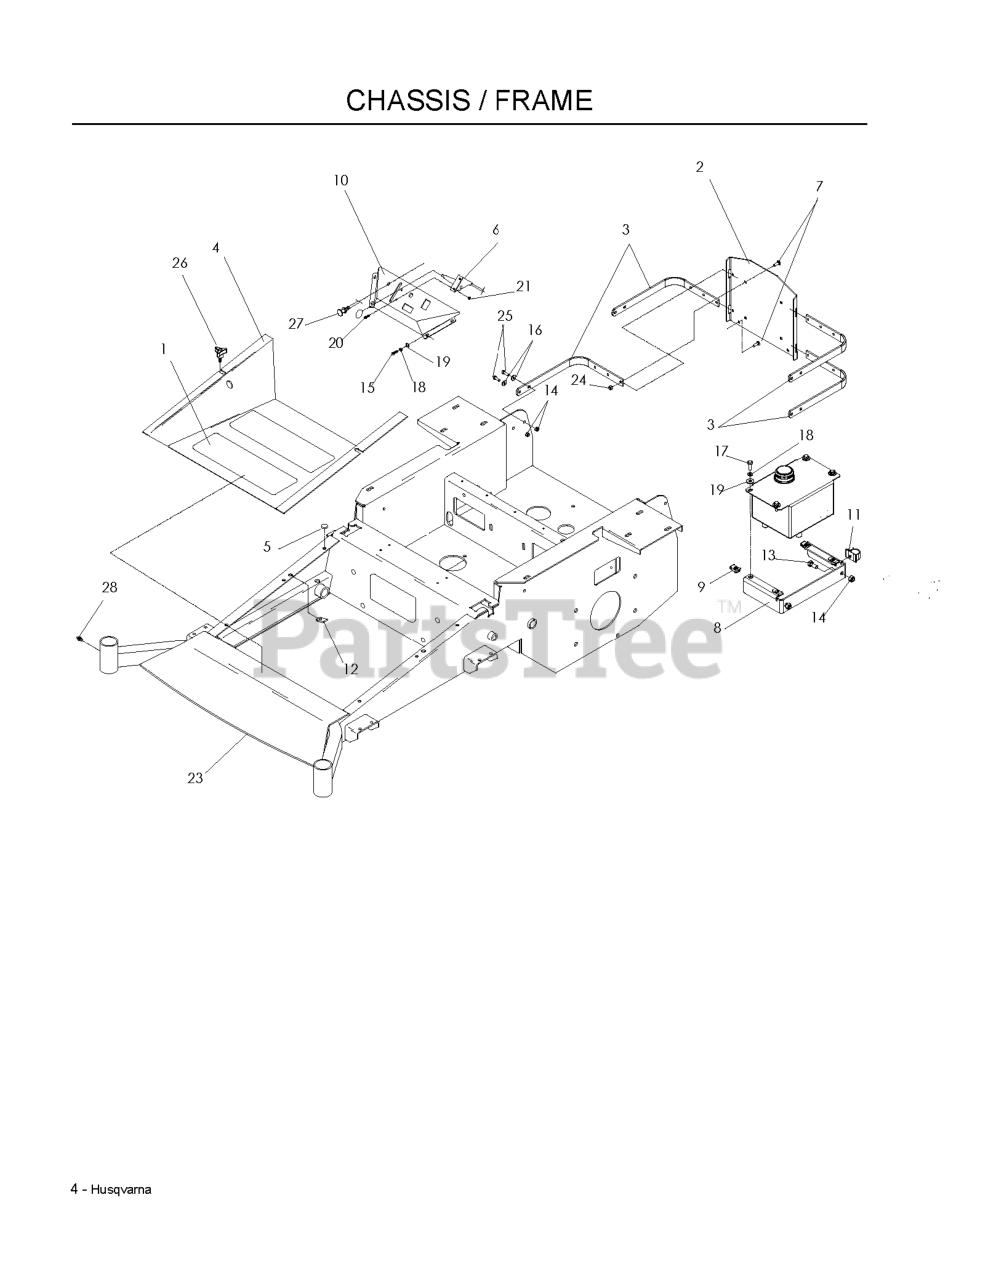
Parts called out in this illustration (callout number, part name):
1	ANTI-SKID PAD
2	XP GUARD, BLACK
3	ENGINE SHROUD BRKT
4	FOOT PLATE WIDMT
5	GROMMET, BUMPER
6	THROTTLE CONTROL W/BALL KNOB
7	BOLT 5/16C X 3/4" CARRIAGE
8	TANK MOUNT
9	1/4C - U TYPE RETAINER
10	CONSLE, ORANGE
11	PUSH-MOUNT WIRE CLIP
12	U-CLIP 5/16-18 NUT RETAINER
13	HCS 5/16C X 3/4
14	NUT 5/16 NYLOC
15	SCREW 1/4 X 5/8
16	WASHER 5/16 FLAT
17	HCS 1/4C X 3/4 HCS
18	LOCKWASHER 1/4"
19	WASHER 1/4 FLAT
20	HCS #10-24 X 1/2
21	NUT 10-24 NYLOC
22	WASHER.LOCK.HVY.HLCL.SPR.5/16
23	FRAME W/DECALS
24	NUT 5/16C CENTERLOCK
25	HCS 5/16C X 1
26	KNOB W/STUD
27	CONTROL-CHOKE 57"
